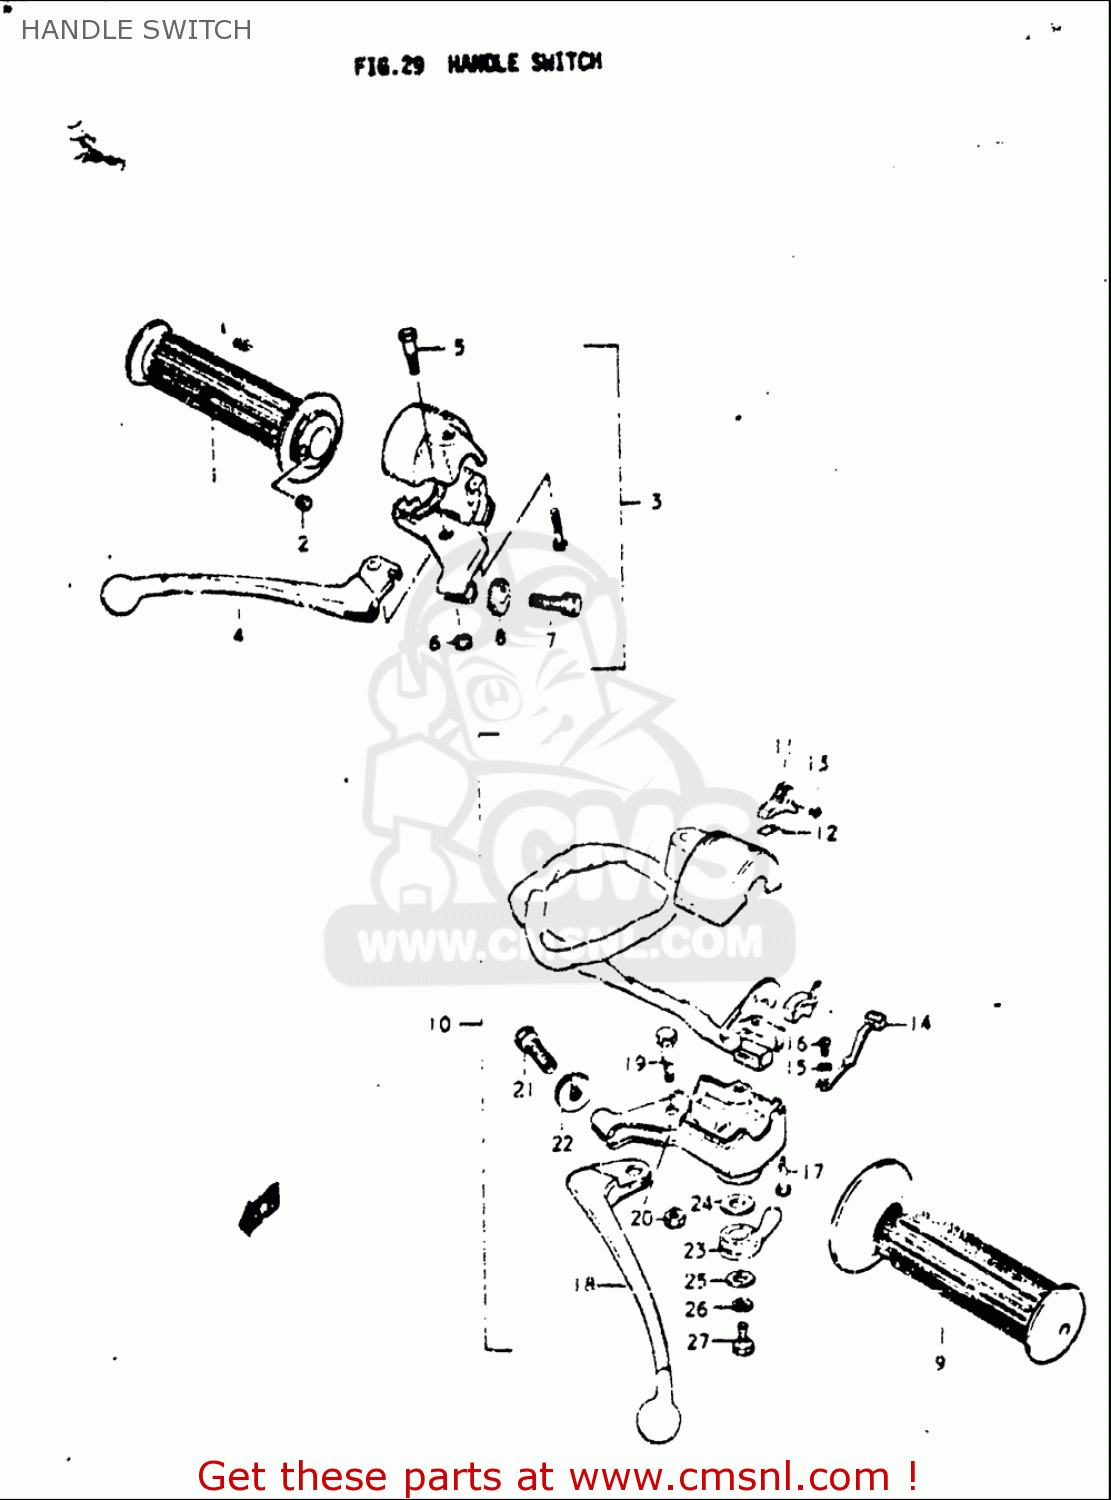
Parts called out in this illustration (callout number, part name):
1	GRIP ASSY,THROTTLE
2	PIECE,THROTTLE END
4	LEVER,BRAKE
5	BOLT
6	NUT
7	ADJUSTER,CABLE
8	NUT,CABLE ADJUSTER
9	GRIP,L
11	KNOB
12	PLATE,SWITCH KNOB
13	SCREW
16	SCREW
17	SCREW
18	LEVER,CLUTCH
19	BOLT
20	NUT
21	ADJUSTER,CABLE
22	NUT,CABLE ADJUSTER
23	LEVER,STARTER
24	WASHER,ADJUSTER
25	WASHER(6.5X16X1)
26	WASHER,LOCK
27	BOLT
